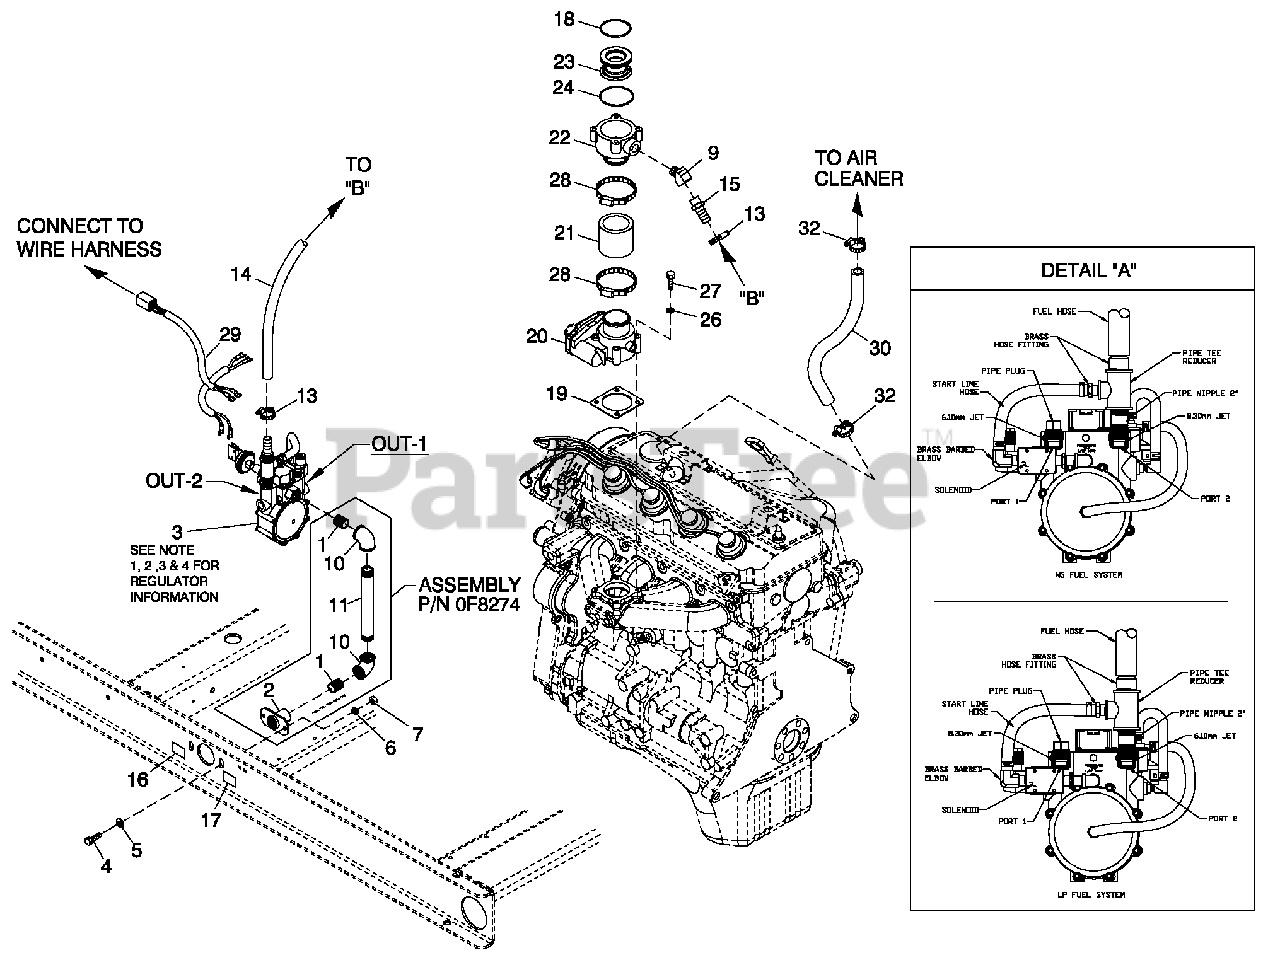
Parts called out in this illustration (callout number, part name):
1	NIPPLE CLOSE 3/4 X 1.375
2	FLANGE FUEL INLET
3	REGULATOR ASSY 2.4L (25KW)
4	SCREW HHC M8-1.25 X 20 G8.8
5	WASHER FLAT 5/16-M8 ZINC
6	WASHER LOCK M8-5/16
7	NUT HEX M8-1.25 G8 CLEAR ZINC
9	STREET EL 45D 1/2 NPT BRASS
10	ELBOW 90D 3/4 NPT
11	NIPPLE PIPE 3/4 NPT X 7
13	CLAMP HOSE #10.56 - 1.06
14	HOSE 3/4 ID SAE-30R2 (18" LG)
15	BARBED STR 1/2 NPT X 3/4
16	DECAL INLET PRESSURE
17	DECALlFUELlINLETlNGl(NATURALlGASlAPPLICATION)
18	O-RING 45.63 ID X 2.62 WIDTH
19	GASKET BOSCH 32
20	ACTUATOR BOSCH 40 GOVERNOR (45 KW)
21	HOSE COOL 2 IN ID 20R4 (45KW)
22	MIXER ACTUATOR 32MM MACHINED(25K)
23	VENTURI THROTTLE 26MM (35 & 45KW)
24	O-RING 47.625 ID X 2.38 WIDTH
26	WASHER LOCK M6-1/4
27	SCREW SHC M6-1.0 X 45 G12.9
28	CLAMPlHOSEl#28l1.32-2.25
29	HARNESS CPL FUEL JUMPER
30	HOSE 3/8 ID SINGLE BRAIDl(18"LG)
32	CLAMP HOSE#10.56-1.06
